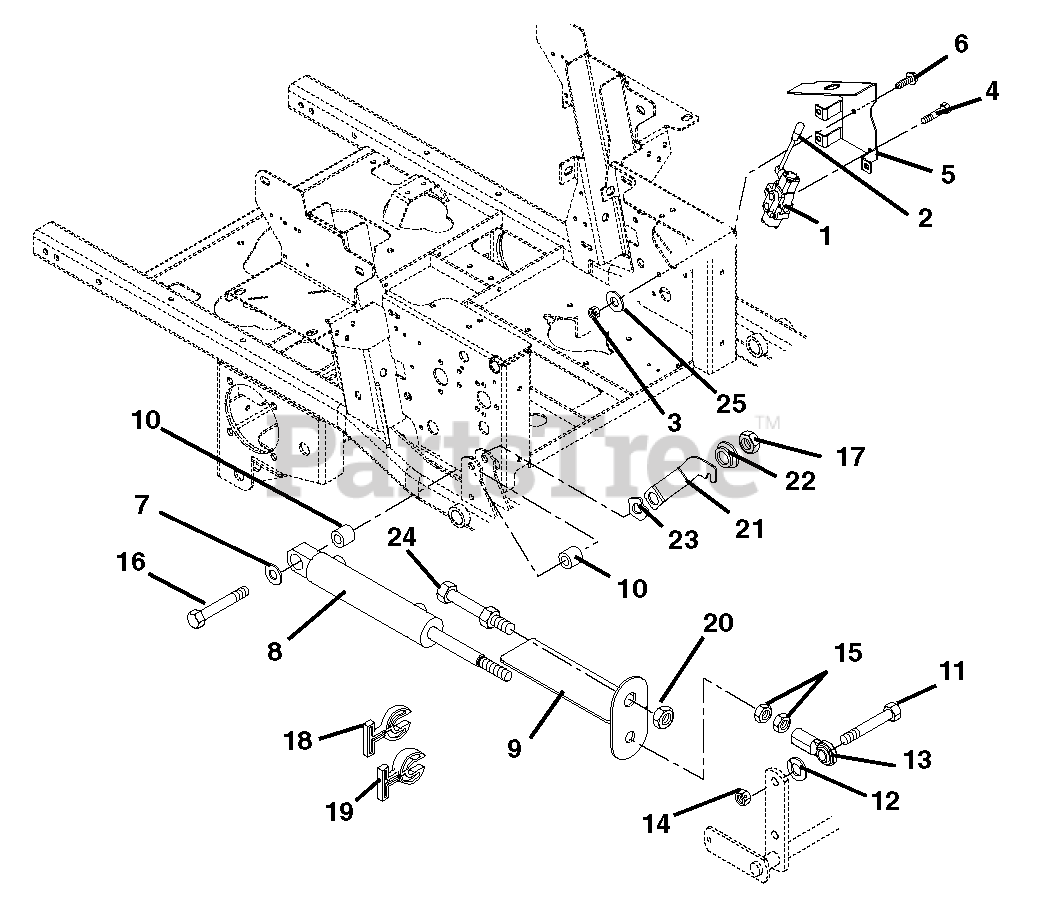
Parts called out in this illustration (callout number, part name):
1	Valve, Hydraulic Lift
2	Knob (Service Only)
3	Nut, Locking Top Flange .31-18
4	Bolt, Hex .31-18 x 2.0 Grade 5
5	Bracket, Valve Mounting
6	Screw, Tapping .38-16 x .50 Hex Washer Head
7	Washer, Flat Steel .515 x 1.625 x .25
8	Cylinder, Hydraulic Lift
9	Strap, Cut Indicator / Guard
10	Bushing .516 x 1.00 x 1.05
11	Bolt, Hex .62-11 x 2.25 Grade 8
12	Washer, Lock .62 x .156
13	Rod End, Right Hand Female .625
14	Nut, Locking Center .62-11
15	Nut, Jam .625-18
16	Bolt, Hex .50-13 x 3.75 Grade 5
17	Nut, Locking Top Flange .50-13
18	Stop, Cylinder .34 Thick
19	Stop, Cylinder .68 Thick
20	Nut, Jam .75-16
21	Latch, Footboard
22	Bushing, Flange .515 x .75 x .275 x 1.12
23	Washer, Wave .076 x 1.12 x .08
25	Washer, Locking .31 x .078 Regular
